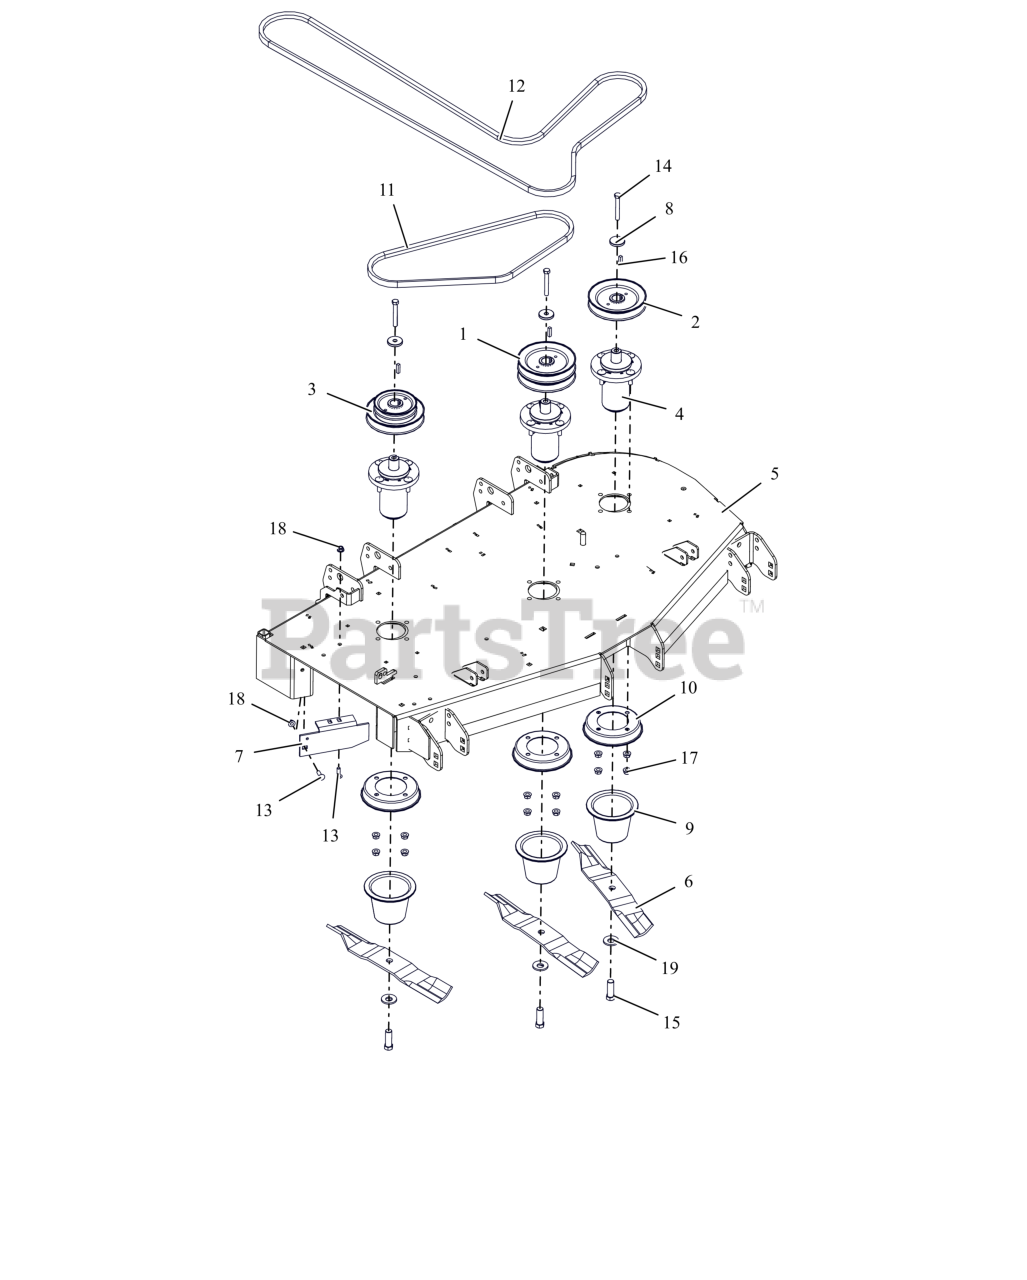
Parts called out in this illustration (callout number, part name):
1	PULLEY, DOUBLE-1"ID X 5.75"OD
2	PULLEY, V-1" ID X 5.75" OD
3	PULLEY, DBL-1"IDX5.75"&4.25"OD
4	ASM, MAINT FREE ALUM SPINDLE
5	WLDMT, PT148 SIDE DISCH DECK (RED)
6	BLADE, 16.19" MOWER (HI-LIFT)
7	44"-48" SIDE DISCH BAFFLE -RED
8	RETAINER, SHEAVE
9	GUARD, SPINDLE LOWER
10	GUARD, SPINDLE TOP
11	V-BELT, B-COGGED
12	V-BELT, B RAW EDGE EPDM
13	BLT,RHSN .31-18X1.00 G5 ZCC
14	BLT, HEX .38-16X2.75 G8 ZCC
15	BLT, HEX .62-18X1.75 G8 ZCC
16	KEY, SQ .25X.25X1.00 RC 40-50
17	NUT-LK-CTR-FLG .375-16 GF ZCC
18	NUT,NYL-FLG .31-18 GF ZCC
19	WSHR-BLVL .669X1.535X.138
